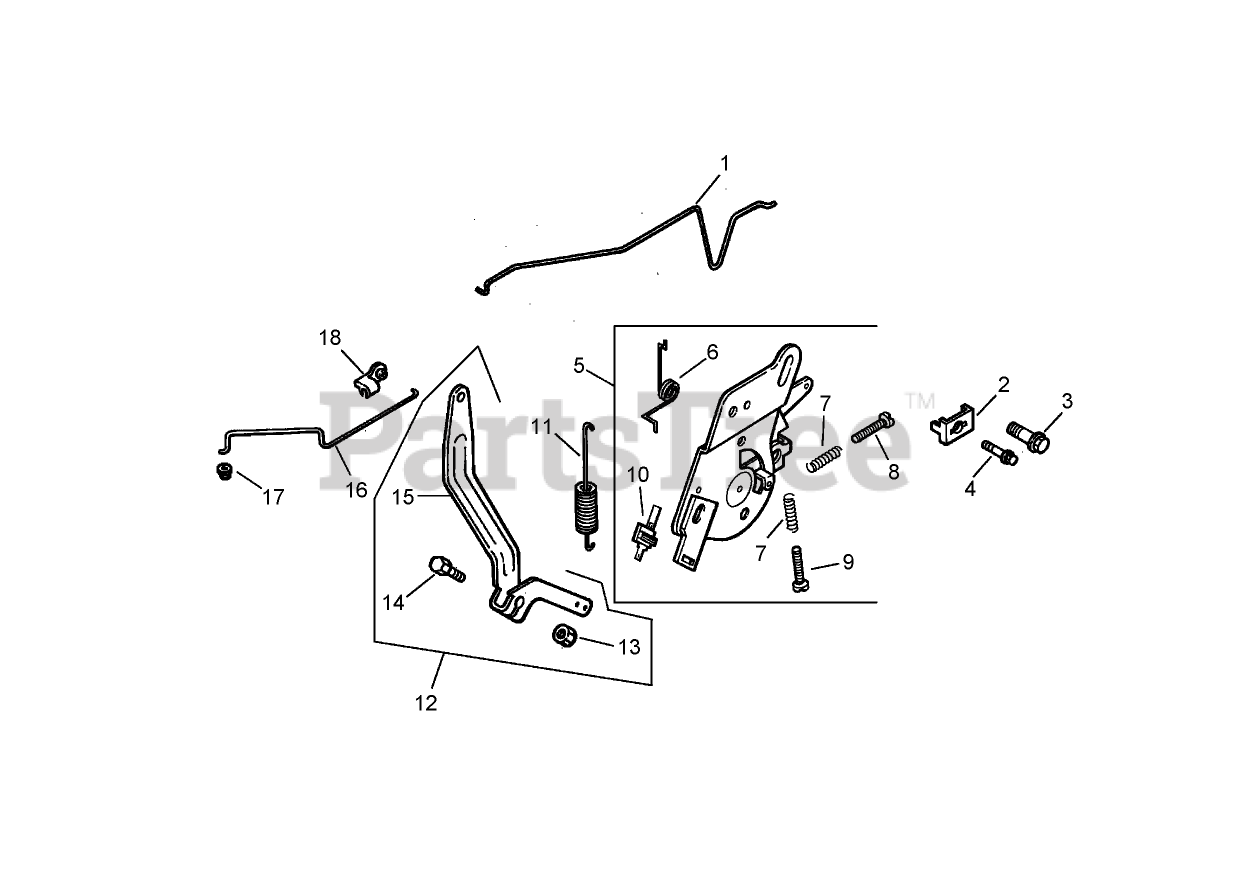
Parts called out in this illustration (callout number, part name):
1	Linkage-Choke
2	CLAMP-CABLE
3	Screw-Socket, 6 Lobed (Thread Forming, M6x1.0x20)
4	SCREW-FLANGE, THREAD FORMING (M5X0.8X16)
5	Speed Control ASM (Includes 6-10)
6	Spring-Return, Choke
7	Spring-Control, Speed
8	Screw-Pan Head (w/loctite)
9	Screw-Pan Head (M4x0.7x20)
10	Terminal-Switch, Kill
11	Spring-Governor
12	Governor Lever Kit (Includes 13-15)
13	Nut-Flange, Hex (1/4-20)
14	Bolt-Square Neck, Round Head (1/4-20x1)
15	Lever-Governor
16	Linkage-Throttle
17	BUSHING-LINKAGE, THROTTLE
18	BUSHING-RETAINING, LINKAGE
